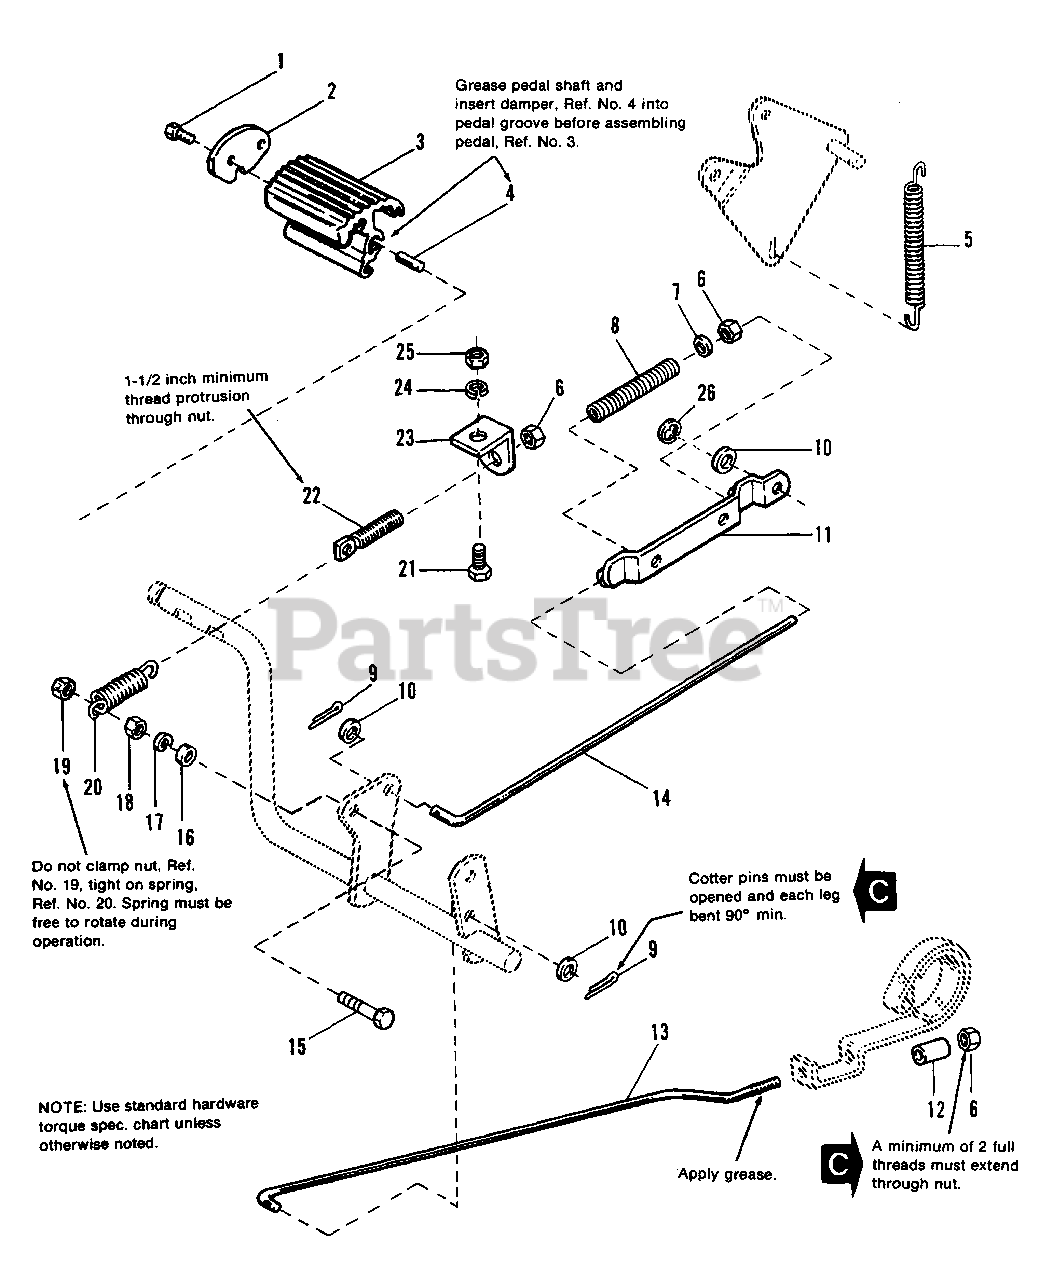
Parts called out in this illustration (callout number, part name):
1	SCREW, Taptite, 1/4-20 x 5/8
2	END PLATE
3	PEDAL, Foot
4	DAMPER, Rubber
5	SPRING, Tension, Idler
6	LOCKNUT, ESNA, 3/8-16
7	WASHER
9	PIN, Cotter, 3/32 x 3/4
10	WASHER, 3/8
11	GUIDE ASSY., Clutch Rod
14	ROD, Clutch
15	CAPSCREW, Hex, 3/8-16 x 1-3/4
17	LOCKWASHER, 3/8
18	NUT, Hex, 3/8-16
19	LOCKNUT, 3/8-16
20	SPRING, Tension
21	CAPSCREW, Hex, 5/16-18 x 1
22	ROD, Tension Adjustment
23	BRACKET, Variator, Spring
24	LOCKWASHER, 5/16
25	NUT, Hex, 5/16-18
